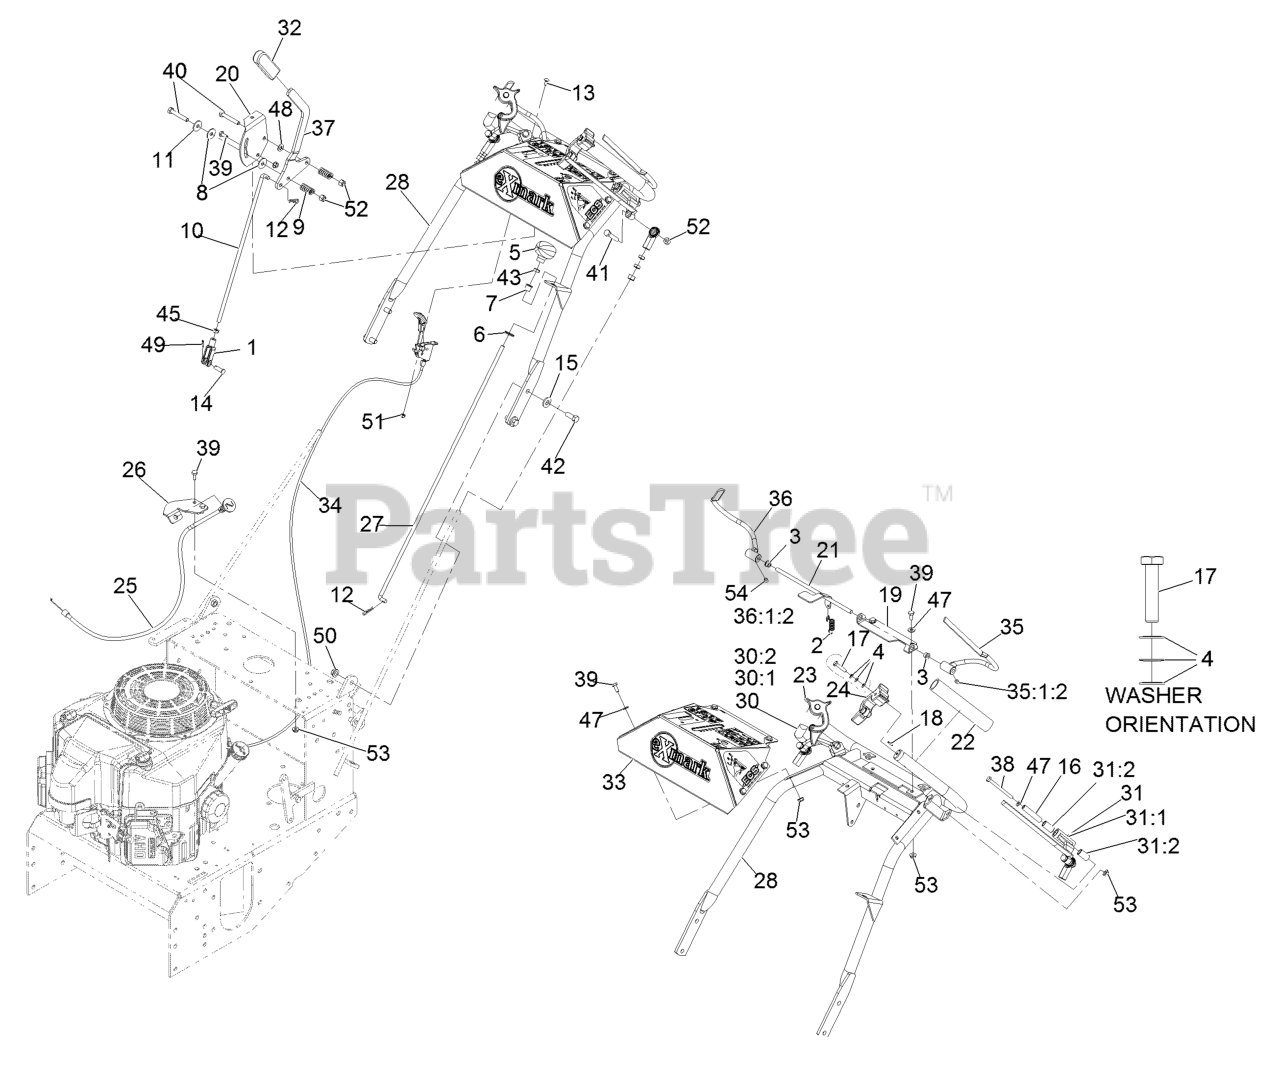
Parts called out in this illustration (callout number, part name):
1	YOKE-ADJUSTABLE
2	SPRING-EXTENSION
3	BUSHING-NYLON
4	WASHER-SPRING
5	KNOB-PUSH / PULL
6	NUT-PUSH
7	BEARING-NYLON
8	WASHER-FRICTION
9	SPRING-COMPRESSION
10	ROD-CONTROL, SPEED
11	WASHER-FRICTION
12	PIN-COTTER
13	BOLT-CARR
14	PIN-CLEVIS
15	WASHER-BELLEVILLE
16	BUSHING-LEVER, DRIVE
17	SCREW-HH
18	PIN-SPRING
19	BRACKET,OPC AXLE
20	BRACKET,SHIFTER SLIDE (PL
21	WLD,OPC LEVER AXLE
22	GRIP-BAR, HANDLE
23	ASM,LATCH RH THUMB
24	ASM,LATCH LH THUMB
25	CABLE-CHOKE
27	LINKAGE,BLADE PUSH/PULL
28	WLD,VH ECS HANDLE
30	DRIVE LEVER-ASM, RH
30:1	WLD,RH DRIVE LEVER
30:2	BUSHING, SLEEVE
31	DRIVE LEVER-ASM, LH
31:1	WLD,LH DRIVE LEVER
31:2	BUSHING, SLEEVE
32	GRIP-HANDLE, STEERING
33	ASM,CONSOLE W/DECALS
34	CONTROL, THROTTLE
35	WLD,LH OPC LEVER
35:1:2	SCREW-SET
36	WLD,RH OPC LEVER
36:1:2	SCREW-SET
38	SCREW-HH
39	SCREW-HH
40	SCREW-HH
41	SCREW-HH
42	SCREW-HH
43	NUT-JAM
45	NUT-JAM
47	WASHER-FLAT
48	WASHER-PLAIN
49	PIN-COTTER
50	NUT-HHF, WHIZ
51	NUT-LOCK, NI
52	NUT-LOCK, NI
54	SCREW-SET
